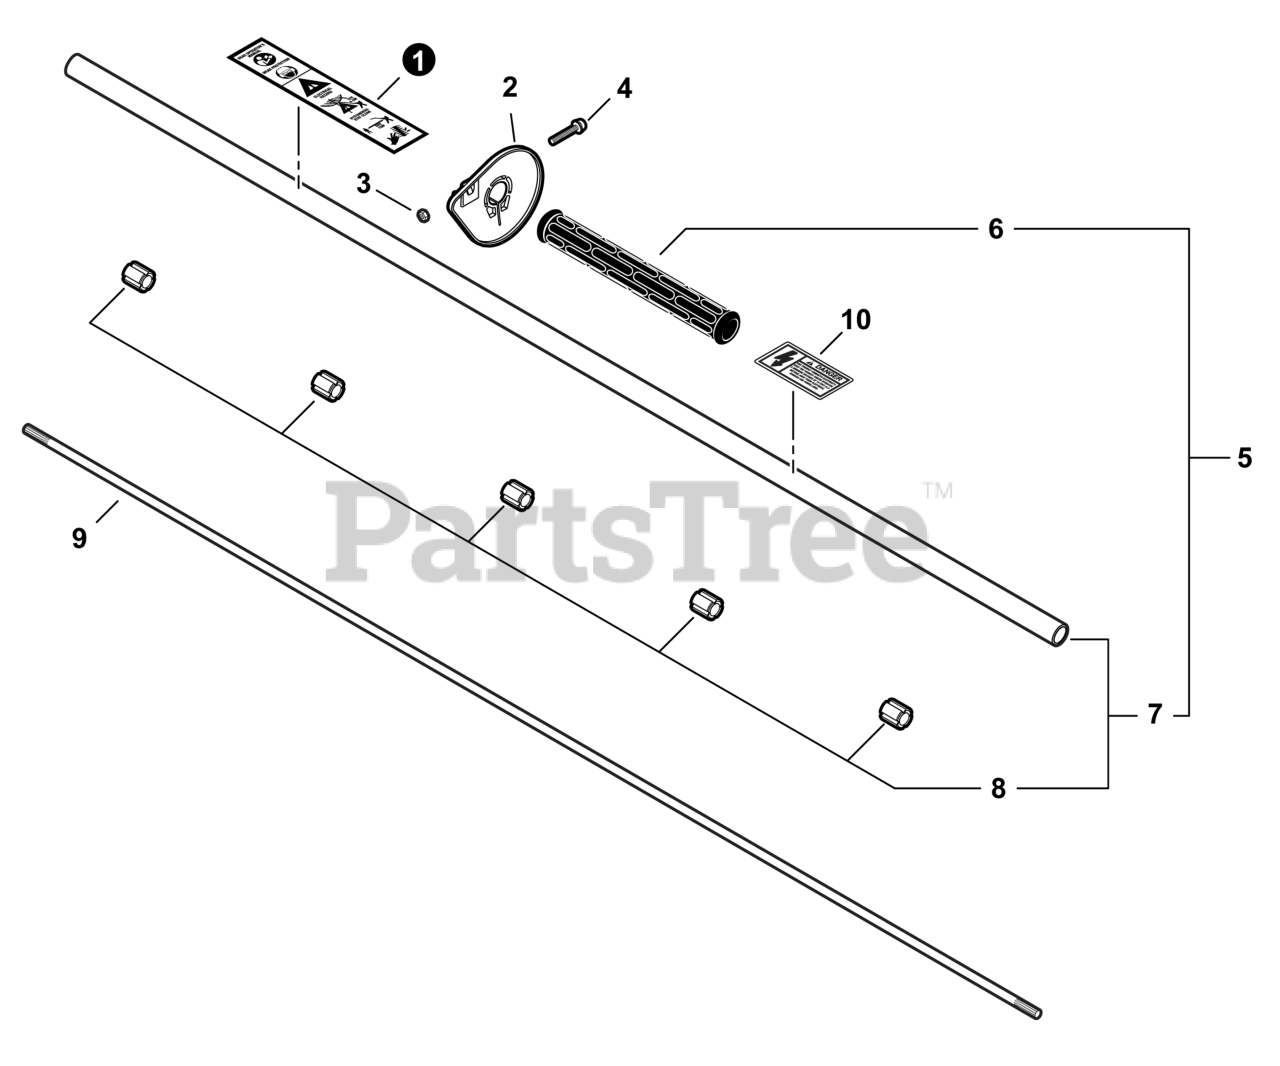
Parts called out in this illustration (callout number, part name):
1	LABEL - CAUTION
2	GUARD, HAND
4	SCREW M5×30
5	MAIN PIPE ASSY WITH GRIP
6	GRIP, FRONT
7	MAIN PIPE ASSY
8	BUSHING
9	MAINSHAFT
10	LABEL - HIGH VOLTAGE
